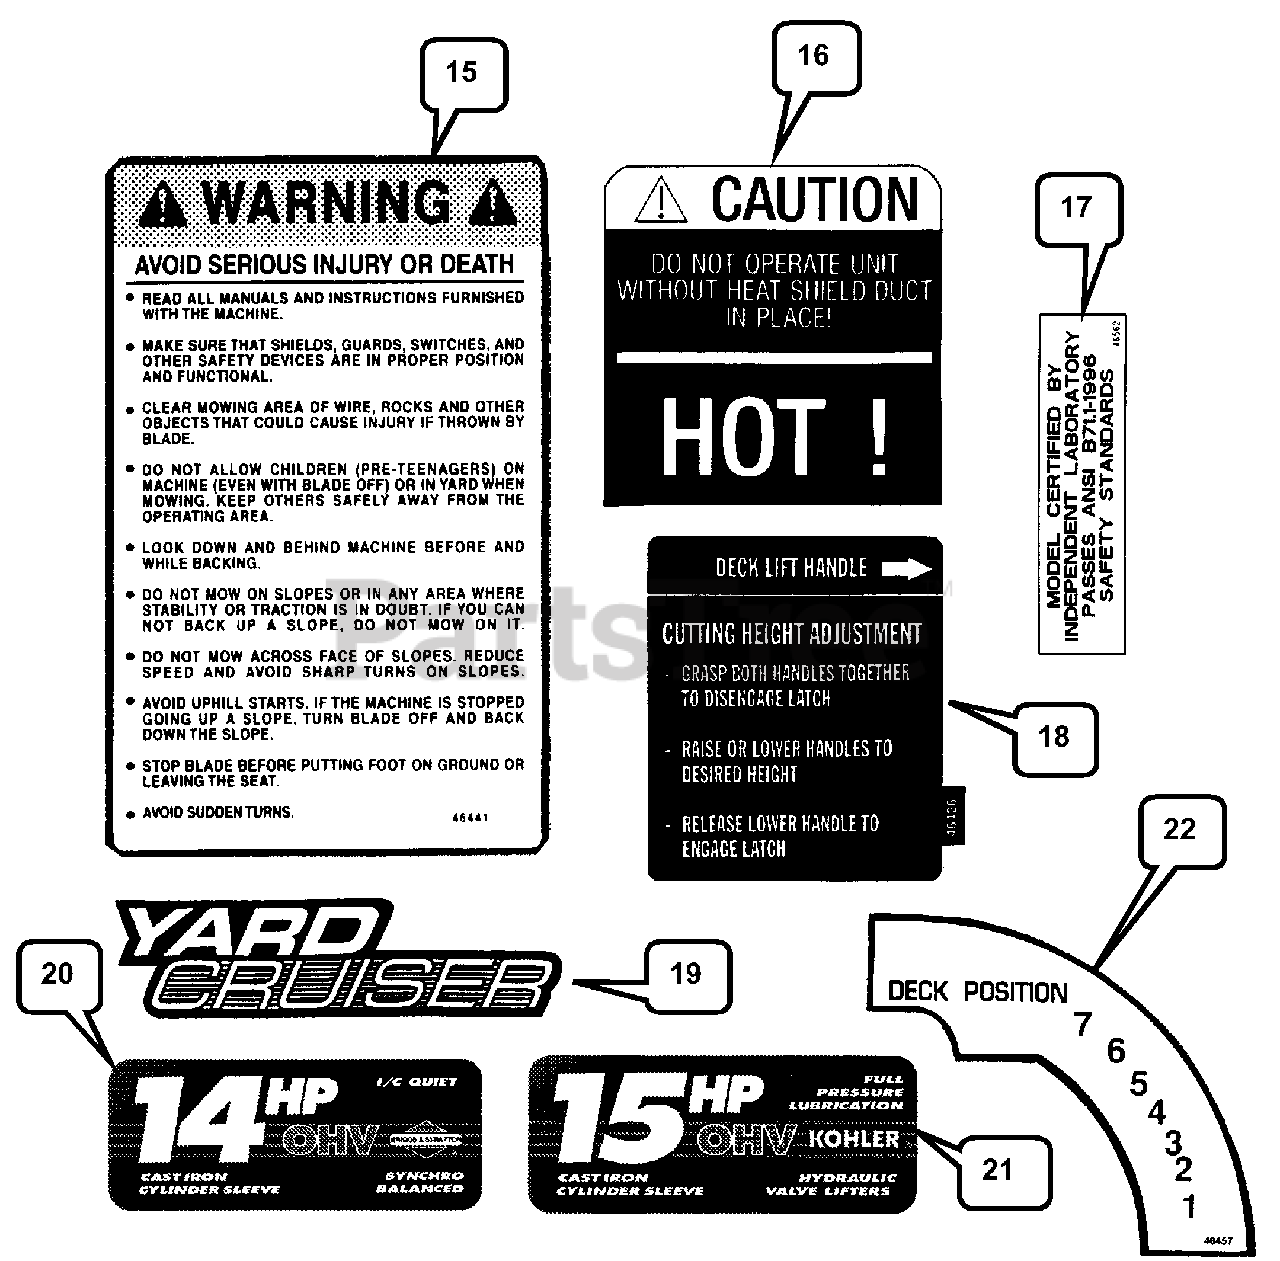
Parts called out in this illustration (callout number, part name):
15	DECAL, Safety Instructions
16	DECAL, Heat Shield
17	DECAL, Certification
18	DECAL, Deck Height
19	DECAL, "Yard Cruiser"
20	DECAL, Briggs 14HP Engine
21	DECAL, Kohler 15HP Engine
22	DECAL, Deck Position
